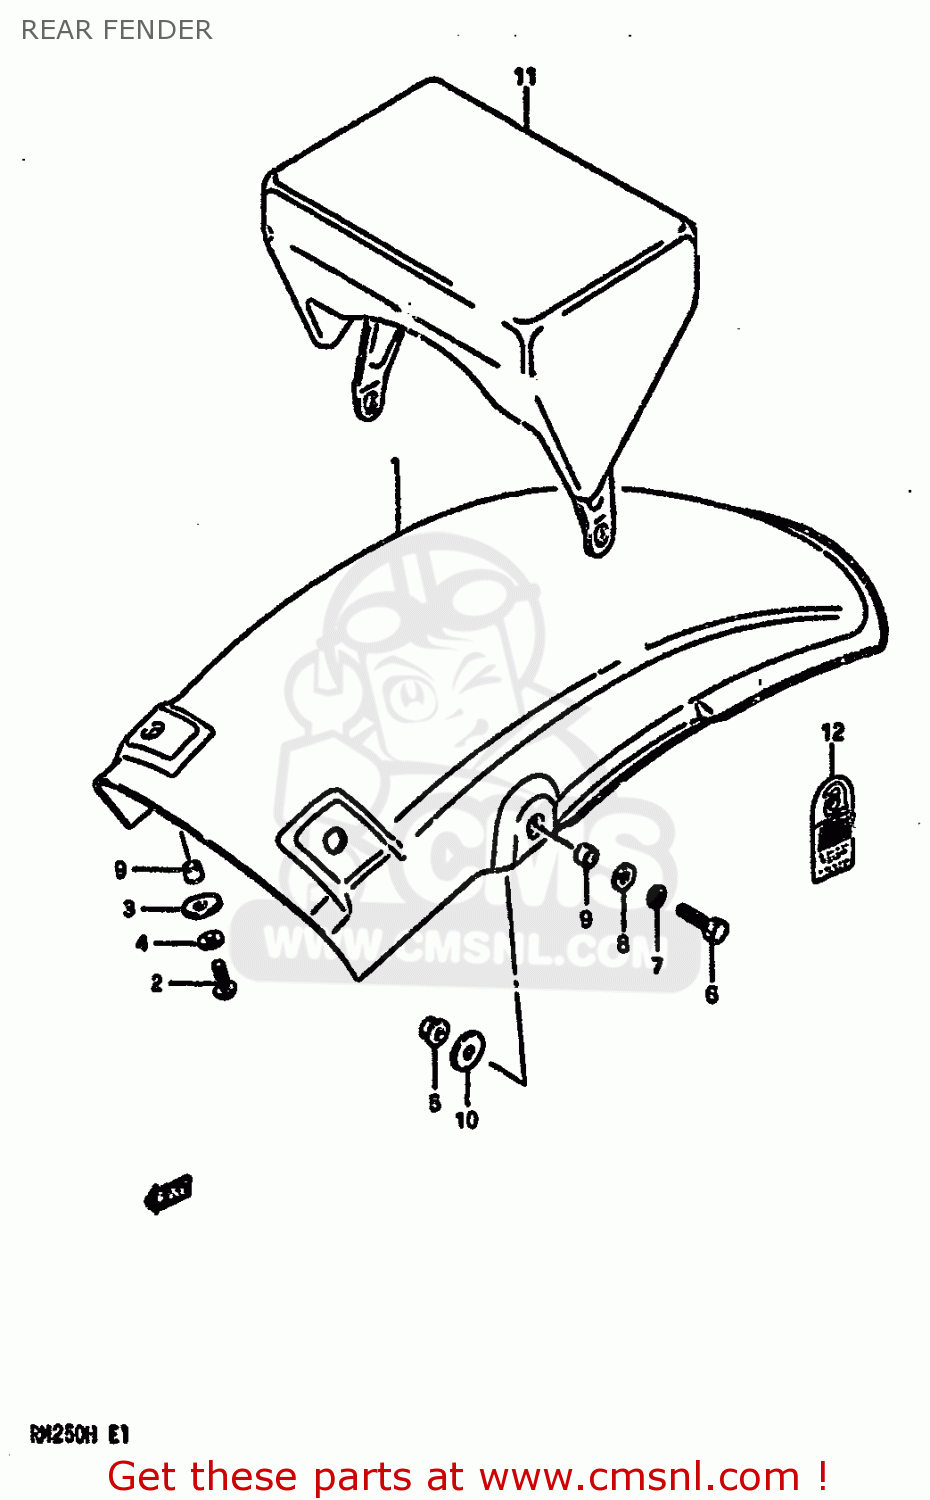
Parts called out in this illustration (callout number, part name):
1	FENDER,REAR
2	SCREW
3	WASHER
4	WASHER,LOCK
5	NUT
6	BOLT
7	WASHER,LOCK
8	WASHER
9	SPACER
10	WASHER (6.5X20X1.2)
11	BAG ASSEMBLY,SEAT TAIL
12	LABEL,ASBESTOS WARNING
